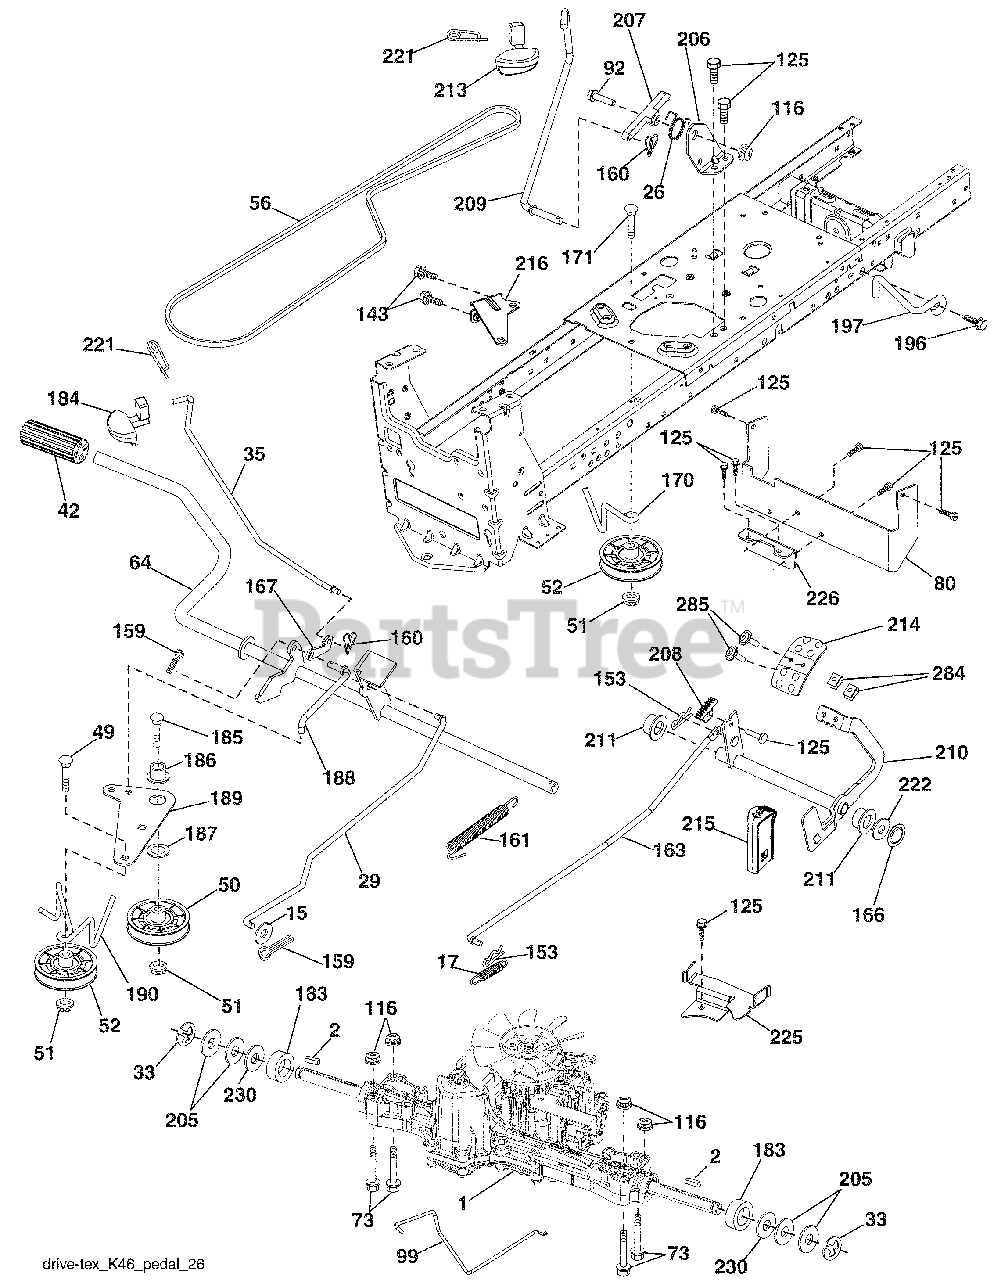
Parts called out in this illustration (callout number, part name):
1	Transaxle, TUFFTORQ K46BT
15	Washer 13/32 x 13/16 x 16 Ga.
17	Spring, Brake
26	Spring Return Cruise
29	Rod, Brake
35	Rod, Brake, Park
42	Cover, Foot Pedal
50	Pulley Idler Flat
51	Lock Nut 3/8-16
52	Idler V-Groove 910" Offset
56	V-Belt, Drive
64	Shaft Asm. Pedal Brake Control
73	Bolt Hex Flghd 5/16-18 Gr. 5
80	Bracket Strap Torque
92	Bolt Fin Hex 5/16-18 unc x 1.25
99	Rod Spring Bypass
116	Nut Lock Hex Flange 5/16-18
125	Screw 5/16-18 x 3/4
143	Screw 5/16-18 x 1/2
153	Retainer Spring
159	Pin Cotter 1/8 x 3/4
160	Retainer Clip
161	Spring, Return, Clutch
163	Rod Pedal Control
166	Nut Push
167	Latch Brake Parking
170	Keeper Belt Centerspan
171	Bolt RDHD SQNK 3/8-16 unc x 2
183	Spacer Split
184	Handle Parking Brake
185	Bolt Rdhd Sqnk 3/8-16 x 2-1/2
186	Spacer Retainer
187	Washer
188	Link Clutch Ground Drive
189	Bellcrank Ground Drive
190	Keeper Bellcrank Ground Drive
196	Screw 3/8-16 x 1
197	Bracket Clutch Anti-Rotation
206	Bracket Mount Latch Cruise
207	Latch Control Cruise
208	Gear Sector Control Cruise
209	Rod Control Cruise
210	Rocker Asm. Pedal Control
211	Bearing Nylon
213	Knob Control Cruise
214	Pedal Forward
215	Pedal Reverse
216	Bracket Pulley Idler
221	Retainer Spring Clip Handle
222	Washer 21/32 x 1-1/4 x 10 Ga.
225	Keeper Belt Trans.
226	Bracket Mount Torque
230	Washer Hardened
284	Nut U-CHNL 1/4-20 550DP .350 PNL
285	Screw PHD 1/4-20 Box Drive
